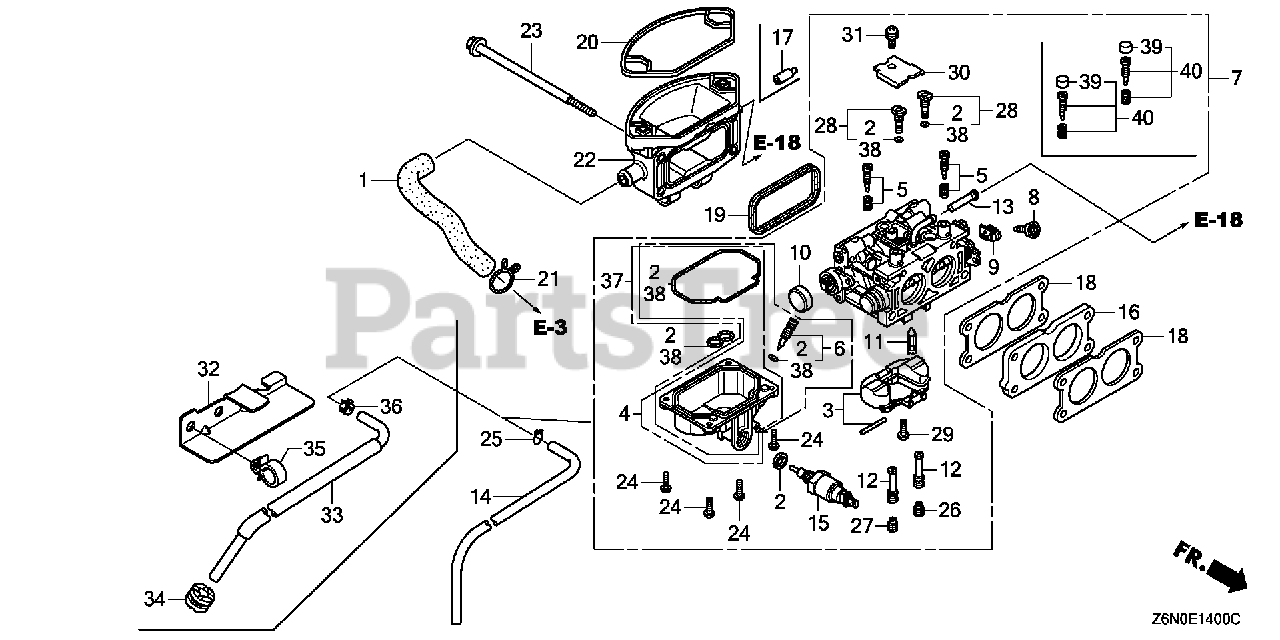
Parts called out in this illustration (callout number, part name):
1	TUBE, BREATHER
2	GASKET SET
4	CHAMBER SET, FLOAT
5	SCREW SET (CARBURETOR NO.)
6	SCREW SET, DRAIN
7	CARBURETOR ASSY. (BK05A C)
8	SCREW, THROTTLE STOP
9	ARM, THROTTLE LINKAGE
10	CAP, CHOKE DUST
11	VALVE, FLOAT
12	NOZZLE, MAIN
13	SCREEN, FUEL STRAINER
14	TUBE, DRAIN
15	VALVE ASSY., SOLENOID
16	INSULATOR, CARBURETOR
18	GASKET, CARBURETOR
19	GASKET, AIR CLEANER
20	SEAL, AIR CLEANER HOUSING
21	CLIP, BREATHER TUBE
22	ELBOW, AIR CLEANER
23	BOLT, FLANGE (6X106)
24	SCREW, PAN (4X12)
25	CLIP, TUBE (B8)
26	JET, MAIN (#110) (CARBURETOR NO.)
26	JET, MAIN (#105)
26	JET, MAIN (#118)
27	JET, MAIN (#105) (CARBURETOR NO.)
27	JET, MAIN (#110) (CARBURETOR NO.)
27	JET, MAIN (#118)
28	JET SET, PILOT (#45)
29	SCREW, FLOAT
31	SCREW-WASHER (5X10)
39	CAP, ADJUSTING SCREW (CARBURETOR NO.)
40	SCREW SET (CARBURETOR NO.)
